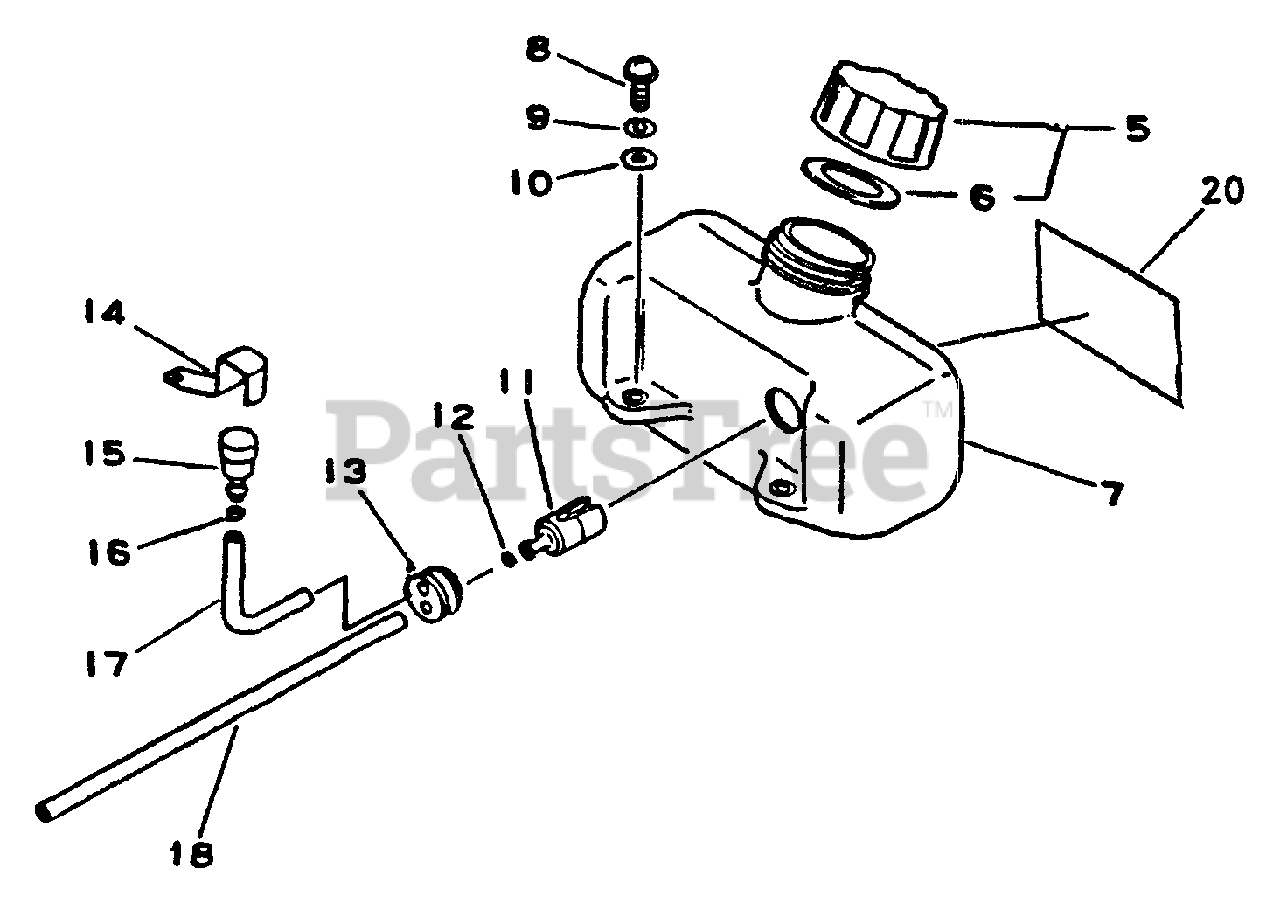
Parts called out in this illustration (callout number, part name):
5	CAP ASSY
6	GASKET, FUEL CAP
7	TANK, FUEL
8	SCREW 5×16
9	WASHER, SPRING 5
10	WASHER 5.5×12×0.8
11	FILTER, FUEL
12	CLIP 6 MM
13	GROMMET, FUEL
15	VENT ASSY
16	RETAINER, PIPE
17	PIPE, FUEL 3×5×80 BLACK
18	PIPE, FUEL
20	LABEL - CAUTION
